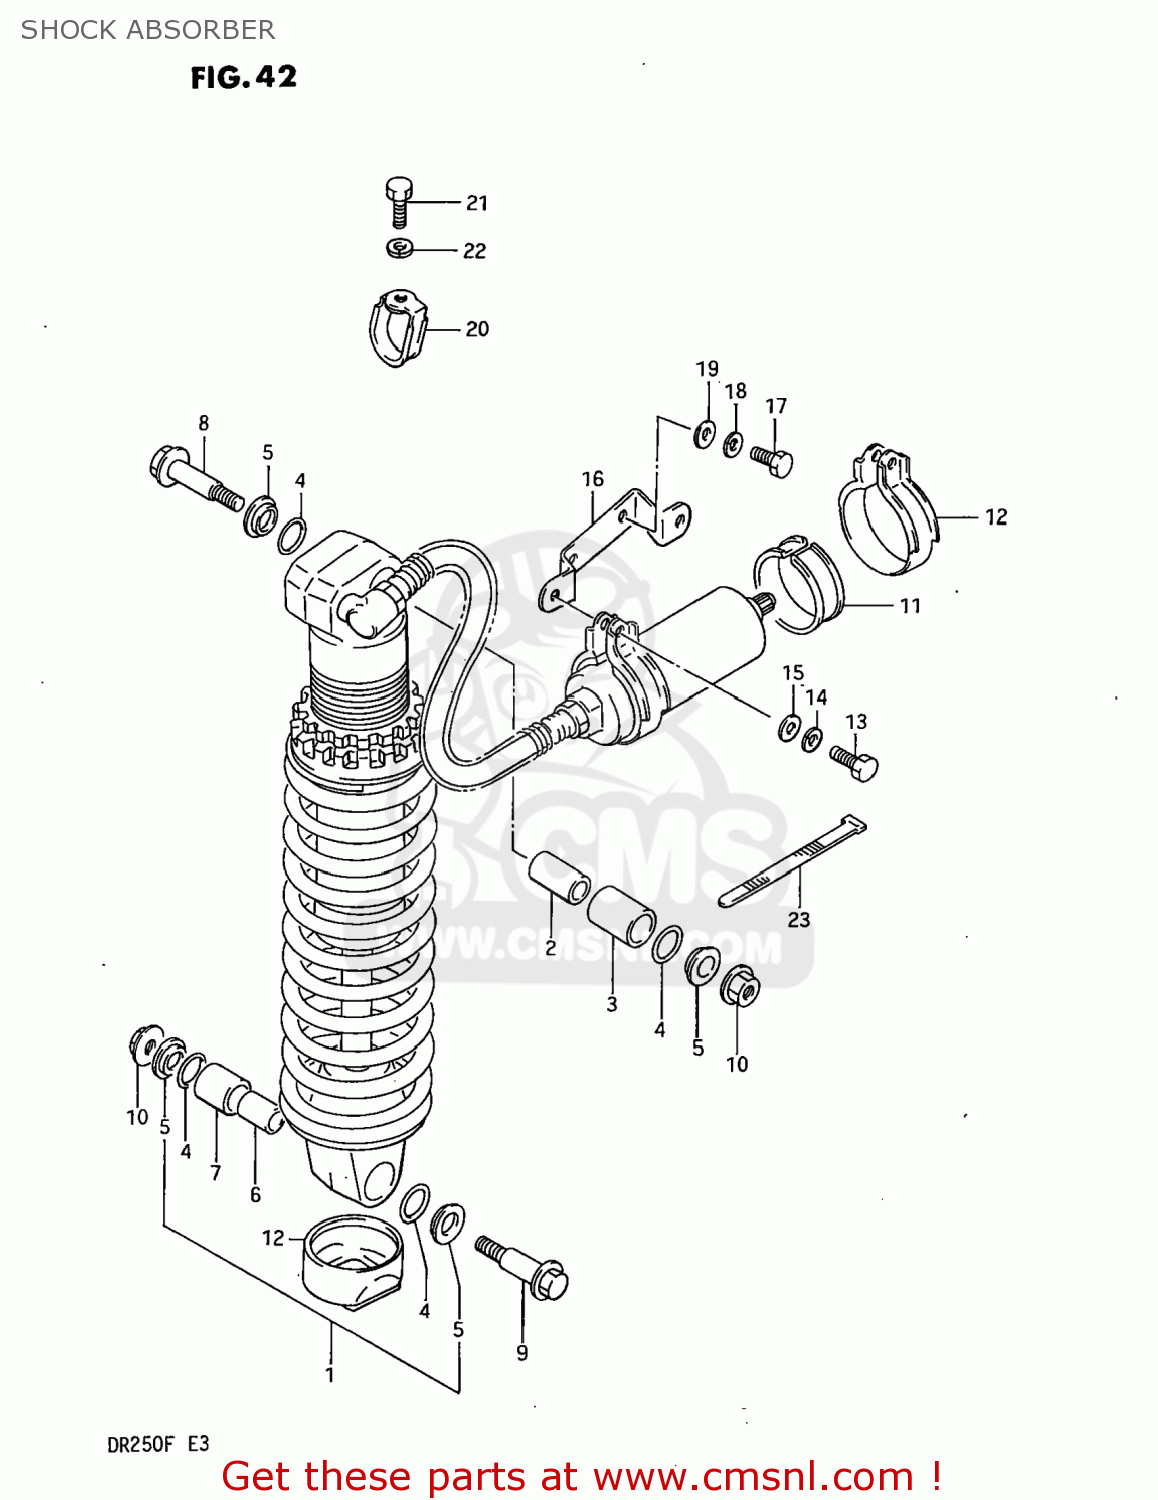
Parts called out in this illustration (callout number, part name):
1	ABSORBER ASSEMBLY,REAR SHOCK
2	BUSH
3	BUSHING,REAR SHOCK,UPPER
4	O-RING,FORK INNER TUBE
5	COLLAR
6	BUSHING,REAR SHOCK ABSORBER
7	BUSHING,REAR SHOCK,LOWER
8	BOLT(10X60)
9	BOLT(10X52)
10	NUT
11	CUSHION,REAR SHOCK ABSORBER TANK
12	BRACKET,RESERVOIR TANK
13	BOLT 6X16
14	WASHER,LOCK
15	WASHER
16	PLATE,BRACKET
17	BOLT
18	WASHER,LOCK
19	WASHER
20	GUIDE,HOSE
21	SCREW 6X12
22	LOCK WASHER
23	CLAMP
